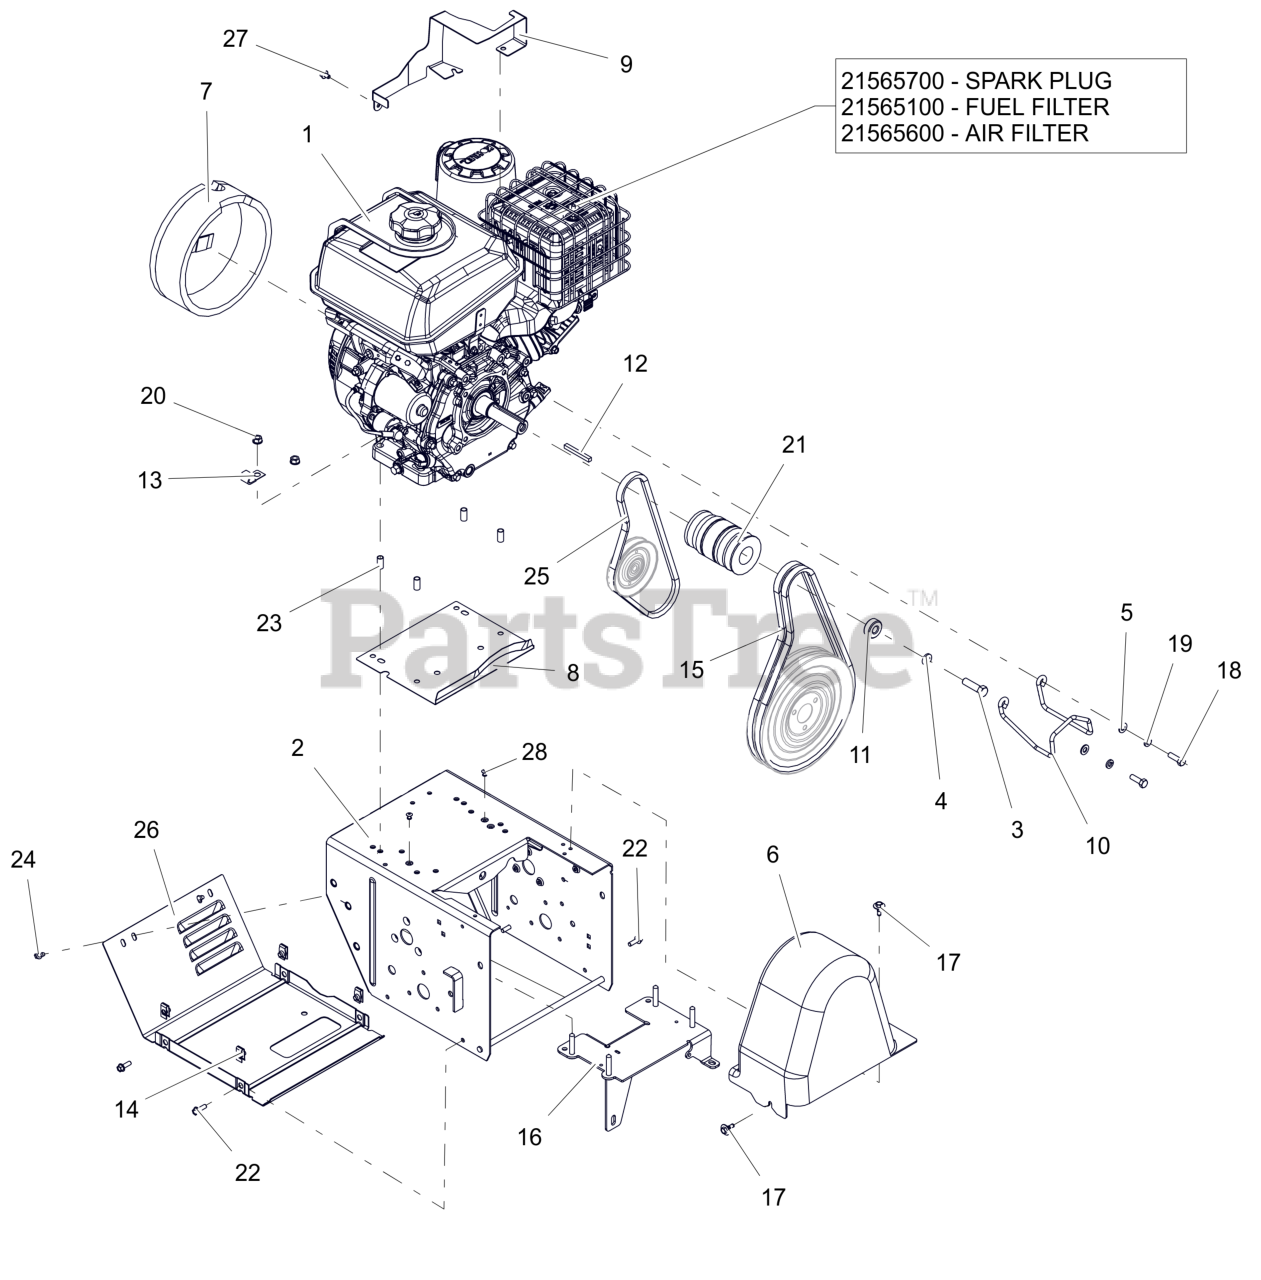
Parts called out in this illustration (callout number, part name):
1	ENGINE, KOHLER - CH395 12V
1	PLUG,SPARK - KOHLER CH395/440
1	FILTER, FUEL (IN TANK)
1	FILTER,AIR - KOHLER CH395/440
2	FRAME, MAIN - PRO (WELDMENT)
3	BLT, HEX .44-20X1.50 G5ZCCEP80
4	WSHR, LK-REG .438X.109 ZCC
5	WSHR,FLT .344X.688X.065 ZCC
6	COVER, BELT-TALL PRO
7	COVER, RECOIL - KOHLER CH395
8	BAFFLE, WATER - LARGE BLOCK
9	BRKT, ENGINE - KOHLER CH395
10	FINGER, BELT
11	BSHG-SPACER .47X1.25X.50
12	KEY .25X.25X2.25
13	J-CLAMP
14	NUT-RTNR .25-20X.56
15	V-BELT, HA-RAW EDGE (SET)
16	BRKT, HYDRO TRANS LG
17	SCR-TAP .25-20X.5 CAPTIVE
18	BLT, HEX 0.3125-24X1 G5 ZCC
19	WSHR, LK-HVY .312X.097 ZCC
20	NUT,LK-CTR-FLG .31-18 GF ZCC
21	SHEAVE, COMBO HYDRO WHEEL
22	BLT, HWH .25-20X.75 G5 ZCC
23	BSHG-SLV .325X.400X.795
24	SCR-TAP .25-20X.50 HWH ZCC
25	V-BELT, 4L-WRAPPED
26	COVER, BOTTOM - VENTILATED
27	BLT, HEX M6-1.0X10 G10.9 ZCC
28	RVT, POP .1875 ZCC
